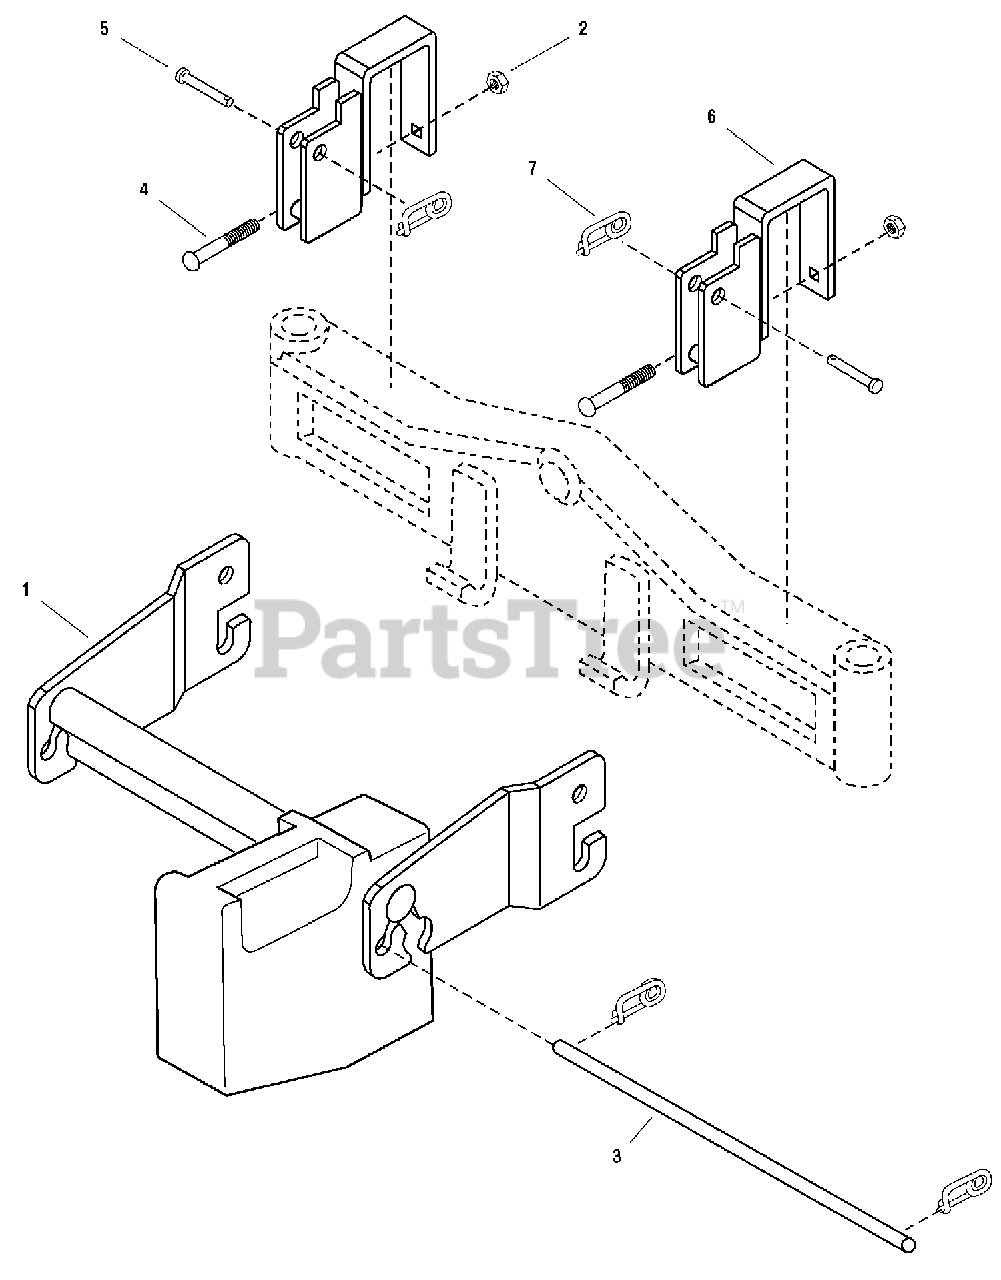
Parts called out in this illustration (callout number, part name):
1	HITCH ASSEMBLY
2	LOCKNUT, 5/16-18
3	ROD, Locking
4	CARRIAGE BOLT, 5/16-18 x 2-3/4
5	PIN
6	CLAMP ASSEMBLY
7	Clip, Safety
